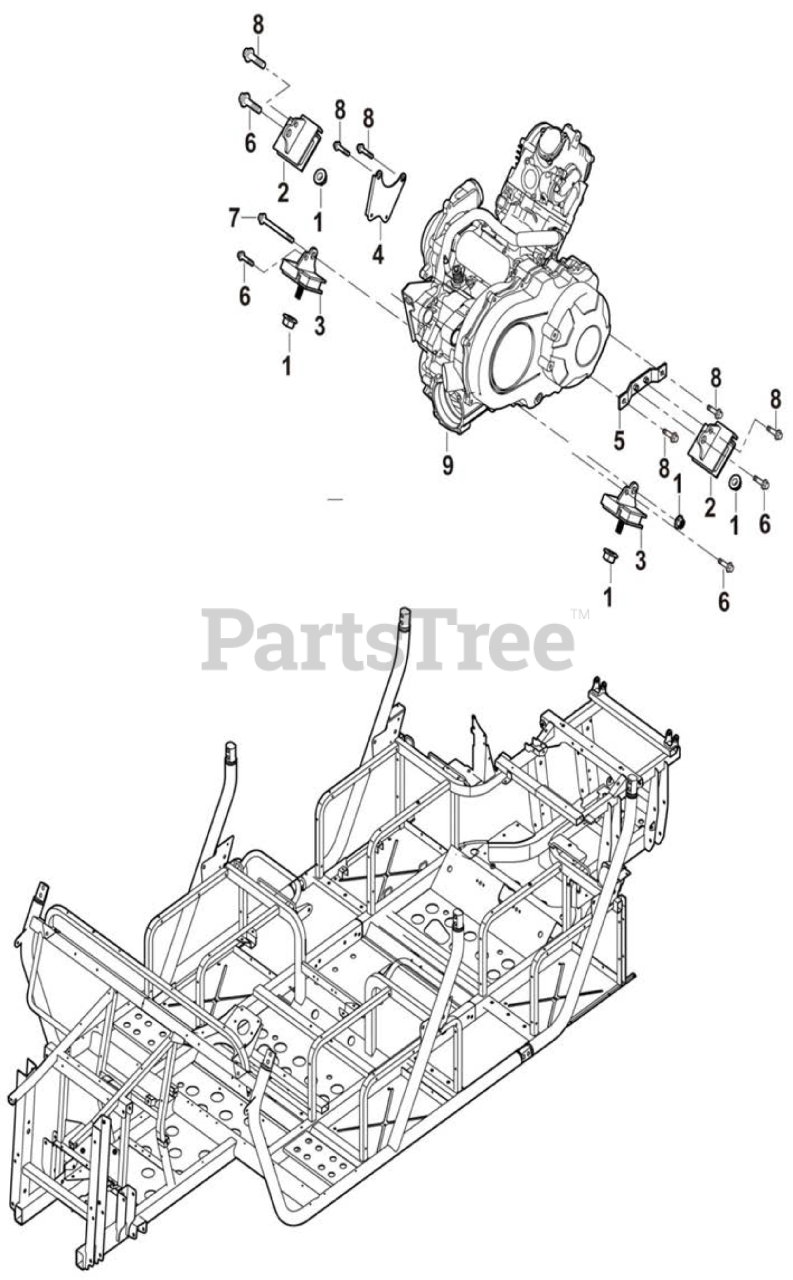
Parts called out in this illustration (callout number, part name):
1	Hexagon Flange Self-Lock Nuts M10x1.25
2	Suspension Support, Engine Front
3	Engine Suspension Bracket
4	Front Left Support ,Engine
5	Upper Engine Suspension III
6	Hexagon Flange Bolt M6X16
7	Hexagon Flange Bolt M10X1.25X170
8	Hexagon Flange Bolt M8X16
9	Engine Assembly
